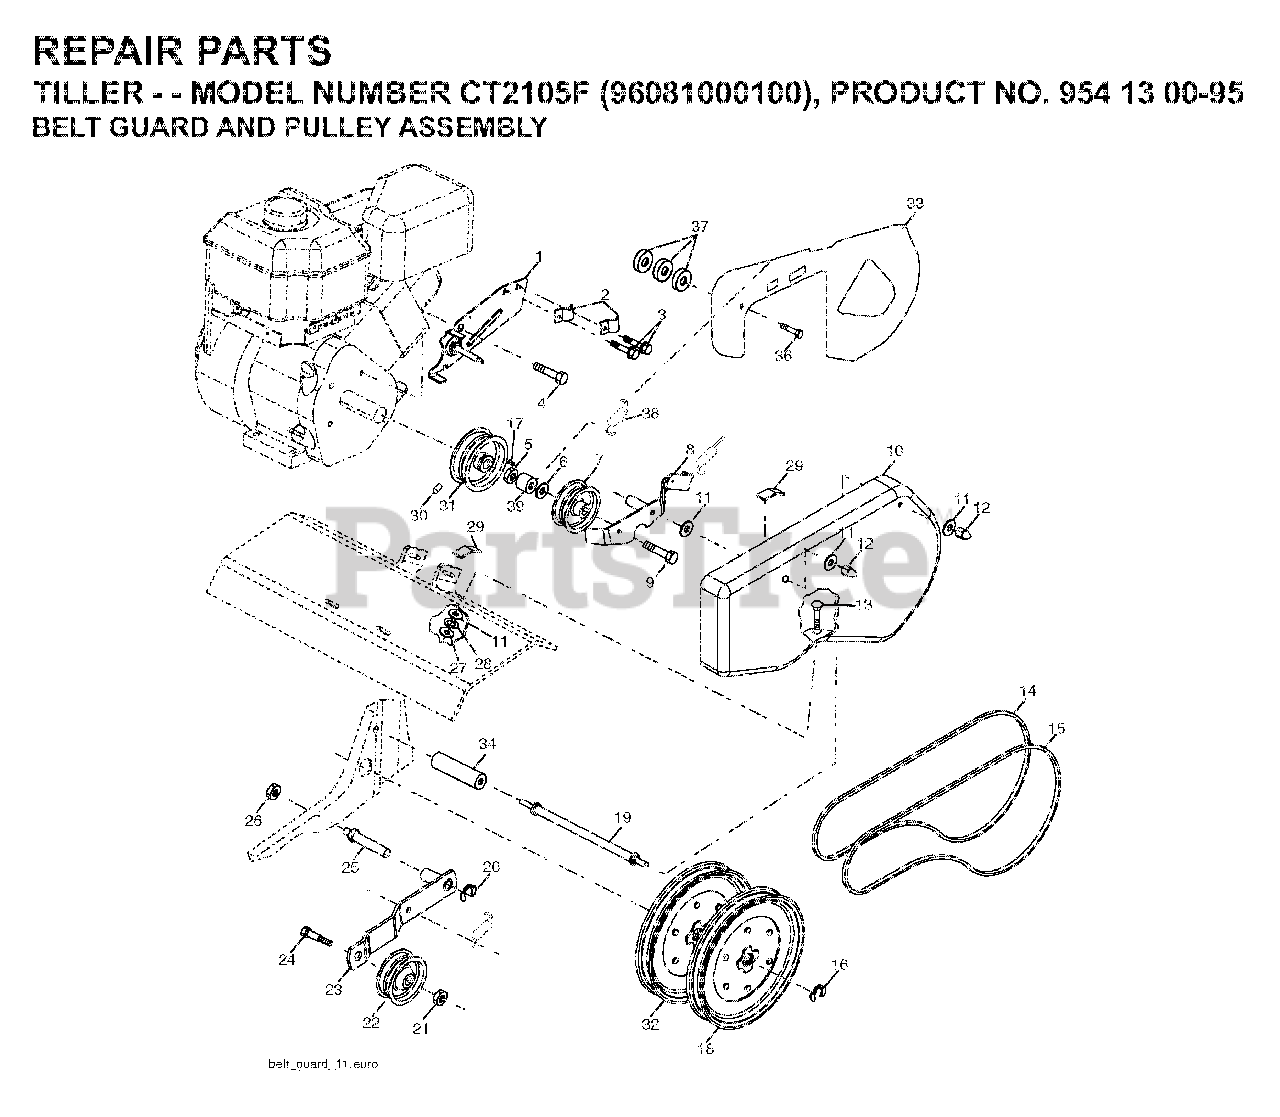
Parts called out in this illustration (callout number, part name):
1	RP BRKT.ASM.GUARD.BELT
2	CONDUIT CLIP T
3	TAPPING SCREW
5	LOCKNUT
7	PULLEY
8	ARM
9	BOLT
11	WASHER
12	CAP
15	BELT
16	RETAINING RING LT
18	SHEAVE,TRANS."D"
19	BOLT.BELT.GUARD
20	KLIP RING TI
21	NUT
22	PULLEY, IDLER
23	ARM, IDLER
25	SHAFT.IDLER.TILLER
26	JAM NUT TI
27	NUT
28	LOCKWASHER
29	PAD IDLER TI
32	SHEAVE.TRANS
37	WASHER
38	SPRING.EXTENSION
